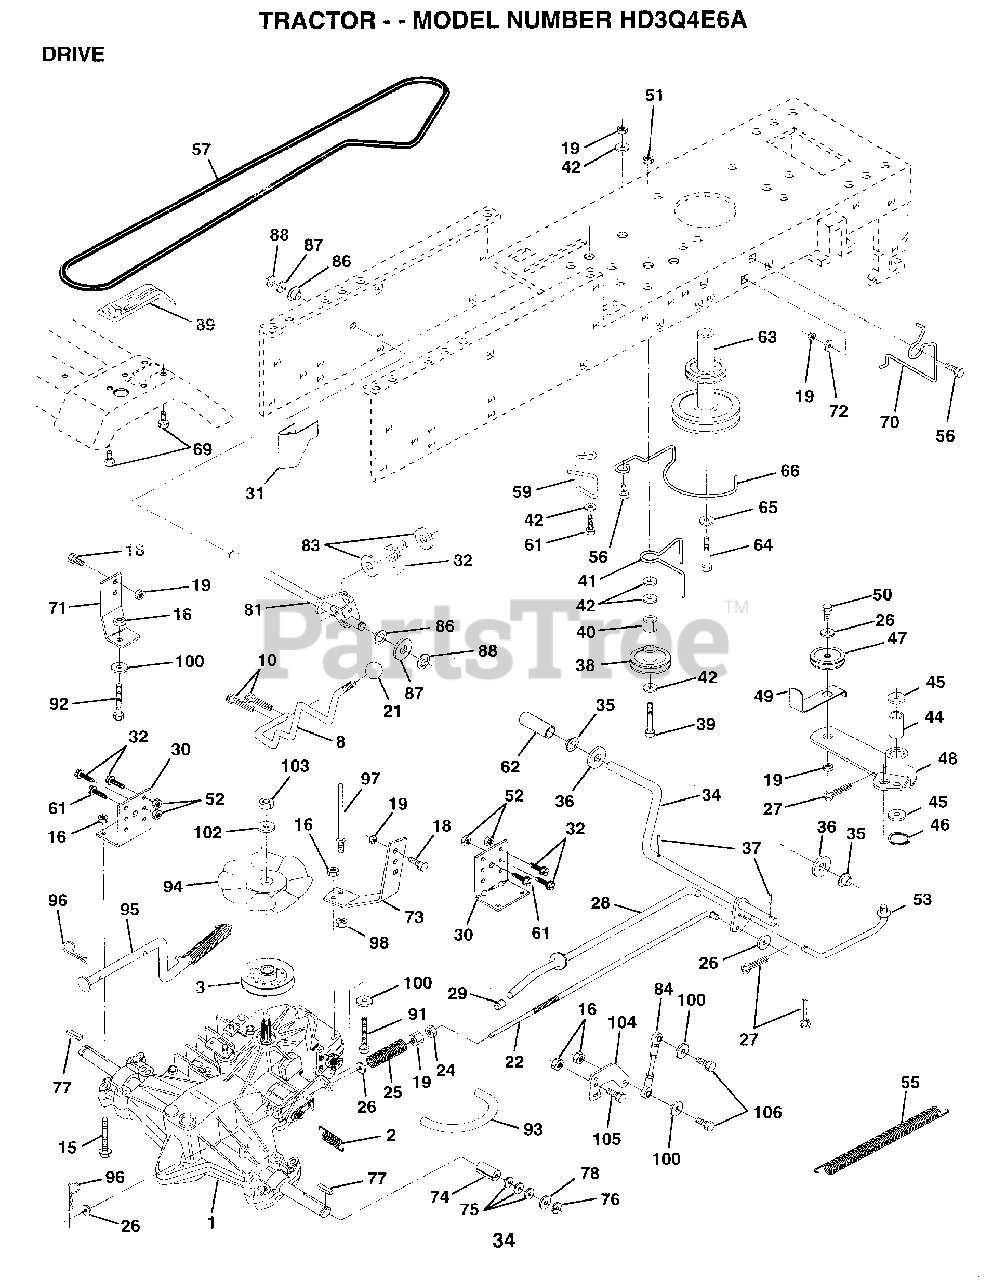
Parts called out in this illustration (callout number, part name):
1	TRANSAXLE.3100650
2	SPRING RET BRAKE
3	PULLEY.TRANSAXLE
8	ROD SHIFT FEND LT
10	PIN COTTER 1/8
15	BOLT.HX.FLG.5/16
16	NUT
18	BOLT
19	NUT
21	KNOB T (1/2-HOLE)
22	ROD.BRAKE.HYDRO.
24	ROD.BRAKE.HYDRO.
24	NUT
25	SPRING ROD LT
26	WASHER
27	COTTER PIN
28	ROD.BRAKE.PARK.LT
29	PLUNGER CAP T
30	TRANSAXLE MTG BKT
31	"KEEPER,BELT LH T"
32	BOLT
34	SHAFT.PEDAL.FOOT
35	NYLON BEARING
36	WASHER LT
38	PULLEY.IDLER.FLAT
39	BOLT
40	SPACER T
41	BELT KEEPER LT
42	WASHER
44	"LY, BEARING"
45	WASHER LT
46	KLIP RING
48	ARM IDLER
49	RETAIN BELT
53	"LINK, CLUTCH T"
55	"SPRING, RETURN LT"
57	"BELT.GD DRV 82"""
58	KEEPER BELT LH
59	KEEPER BELT CNTSP
61	SCREW
62	PEDAL COVER T
63	PULLEY.ENGINE
64	BOLT
65	LOCKWASHER
66	KEEPER.BELT.ENG.L
69	SCREW HEXWSH H-L
70	KEEPER BELT ENG
71	STRAP TORQ LH HYD
72	WASHER
72	"SPRING,TORSION"
73	STRAP TORQ RH HYD
74	SPACER SPLIT
75	WASHER
76	E-RING LT
77	SQUARE KEY
78	WASHER
83	WASHER
84	ROD.TIE.BALL.4.75
86	BUSHING
87	WASHER D
88	KLIP RING
92	HEX BOLT
93	"LINE FUEL HYD 4"""
94	"FAN 7"" HYDRO"
96	RETAINER M
97	BOLT KEEPER RH
98	NUT
100	WASHER M
102	WASHER BELLEVILLE
104	ARM CONTROL HYDRO
105	SCREW CAP 5/16-18
106	BOLT
